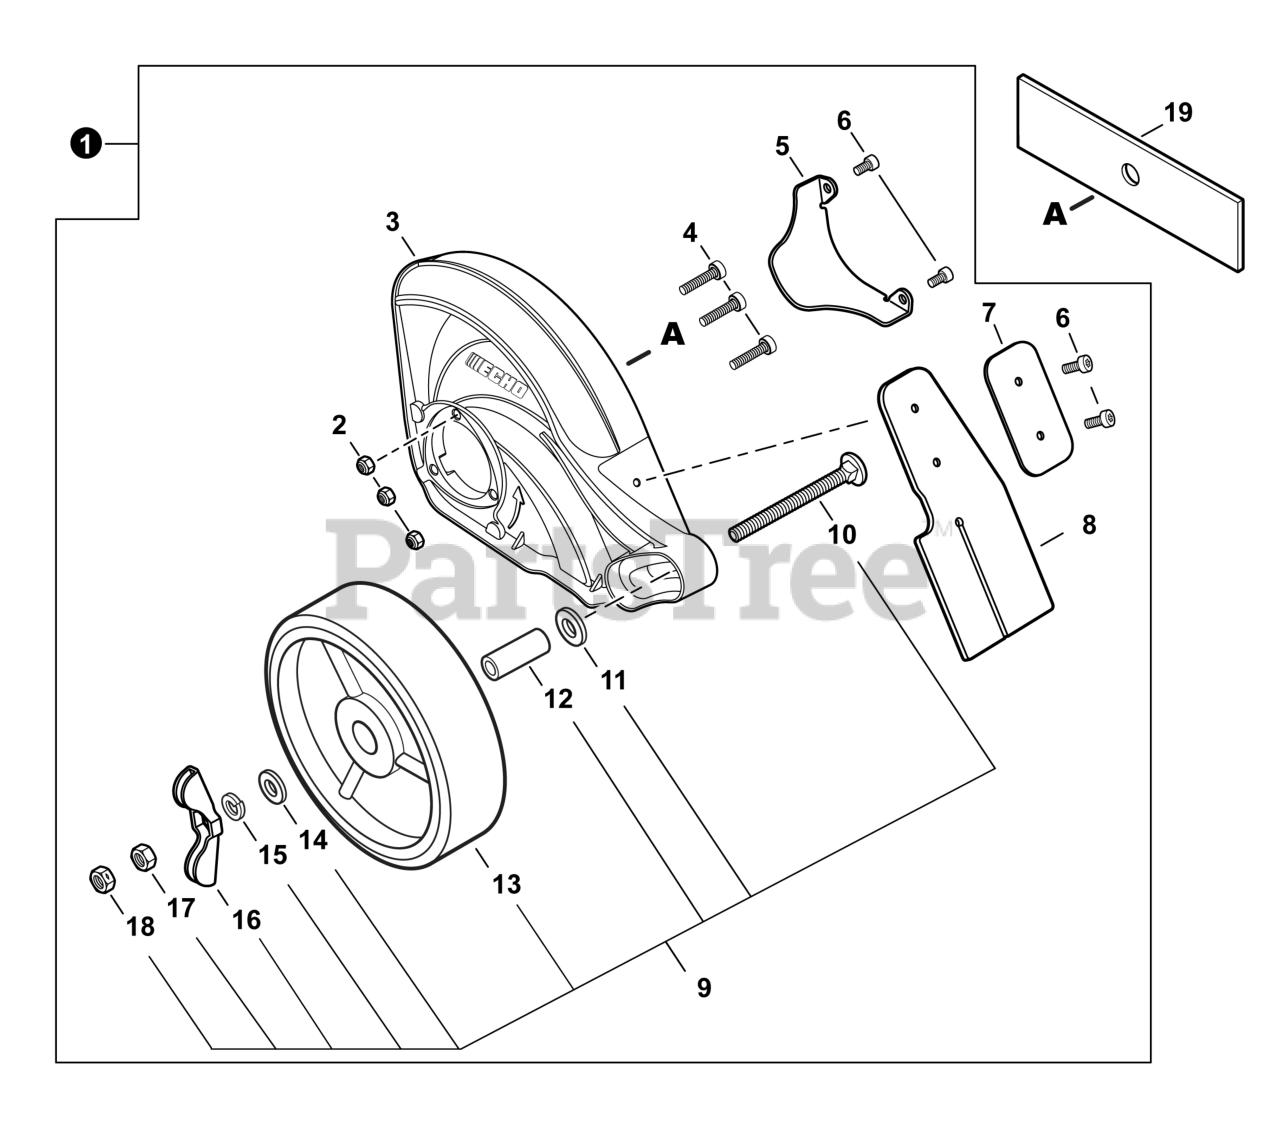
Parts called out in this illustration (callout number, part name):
1	SHIELD KIT, EDGER
2	NUT, LOCK M5
3	SHIELD, BLADE
4	BOLT, TORX 5x20
5	GUARD, SHIELD
6	BOLT, TORX 4x12
7	PLATE, FLAP
8	FLAP, DEBRIS
9	WHEEL KIT
10	BOLT M8-1.25x80 MM
11	WASHER M10
12	COLLAR 12
14	WASHER 8
15	WASHER, SPRING 8
16	KNOB, FASTENER
18	NUT, LOCK M8
19	BLADE - 2 PK
